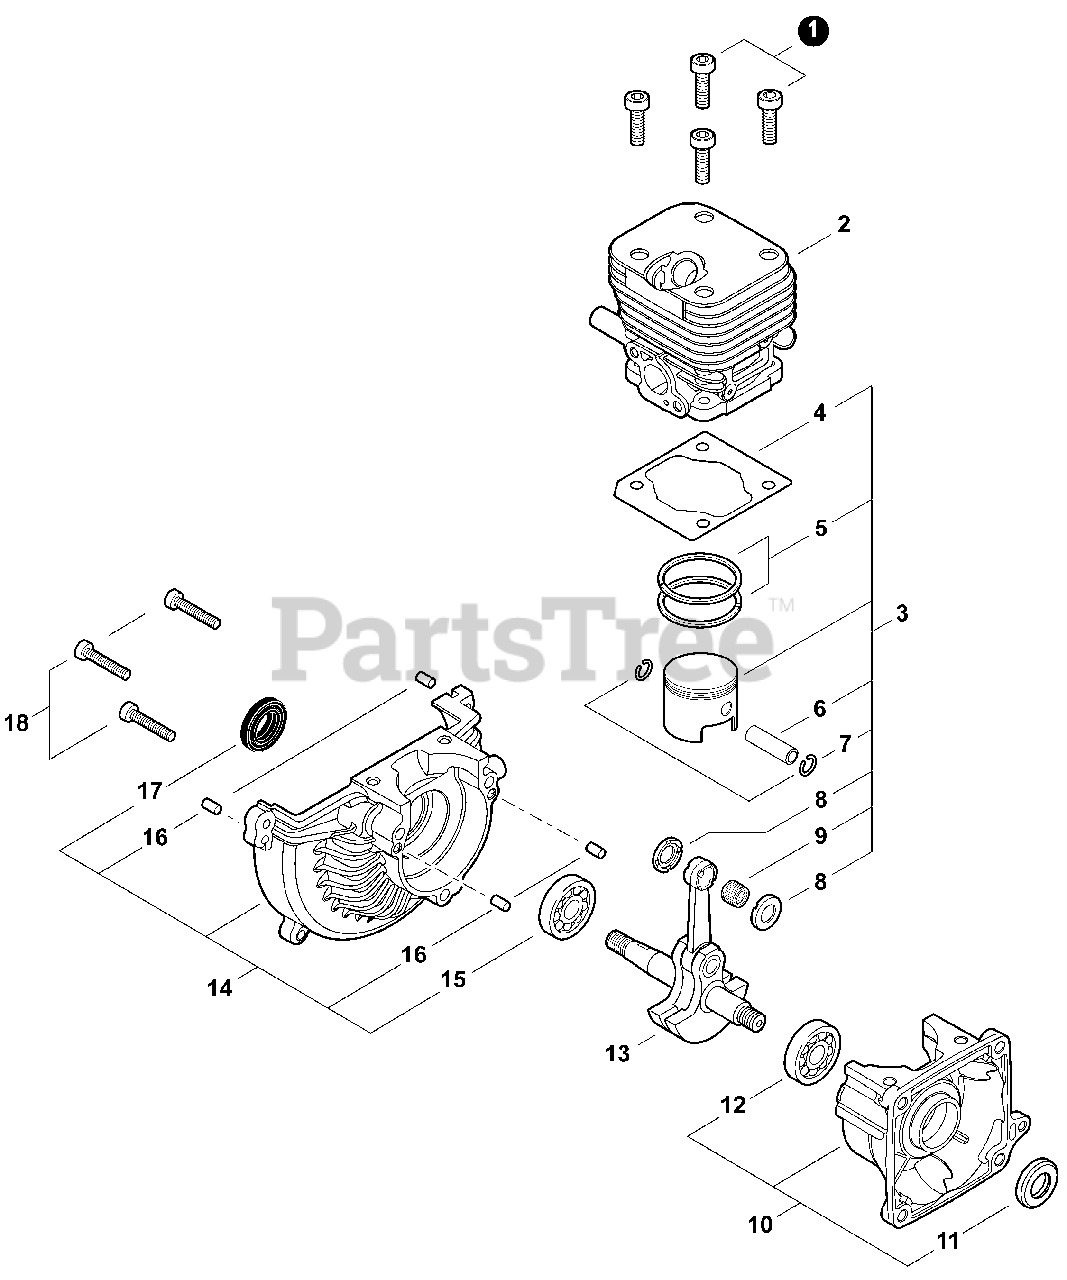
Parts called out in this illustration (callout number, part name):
1	BOLT 5×16
2	CYLINDER ASSY
3	PISTON KIT
4	GASKET, CYLINDER
5	RING, PISTON
6	PIN, PISTON
7	RING, SNAP
8	WASHER, THRUST 9
9	BEARING, NEEDLE 9
10	CRANKCASE ASSY, S
11	SEAL, OIL
12	BEARING, BALL 6201 C3
13	CRANKSHAFT
14	CRANKCASE ASSY, M
15	BEARING, BALL 6201 C3
16	PIN, LOCATING 4×8
17	SEAL, OIL
18	BOLT 5×25
